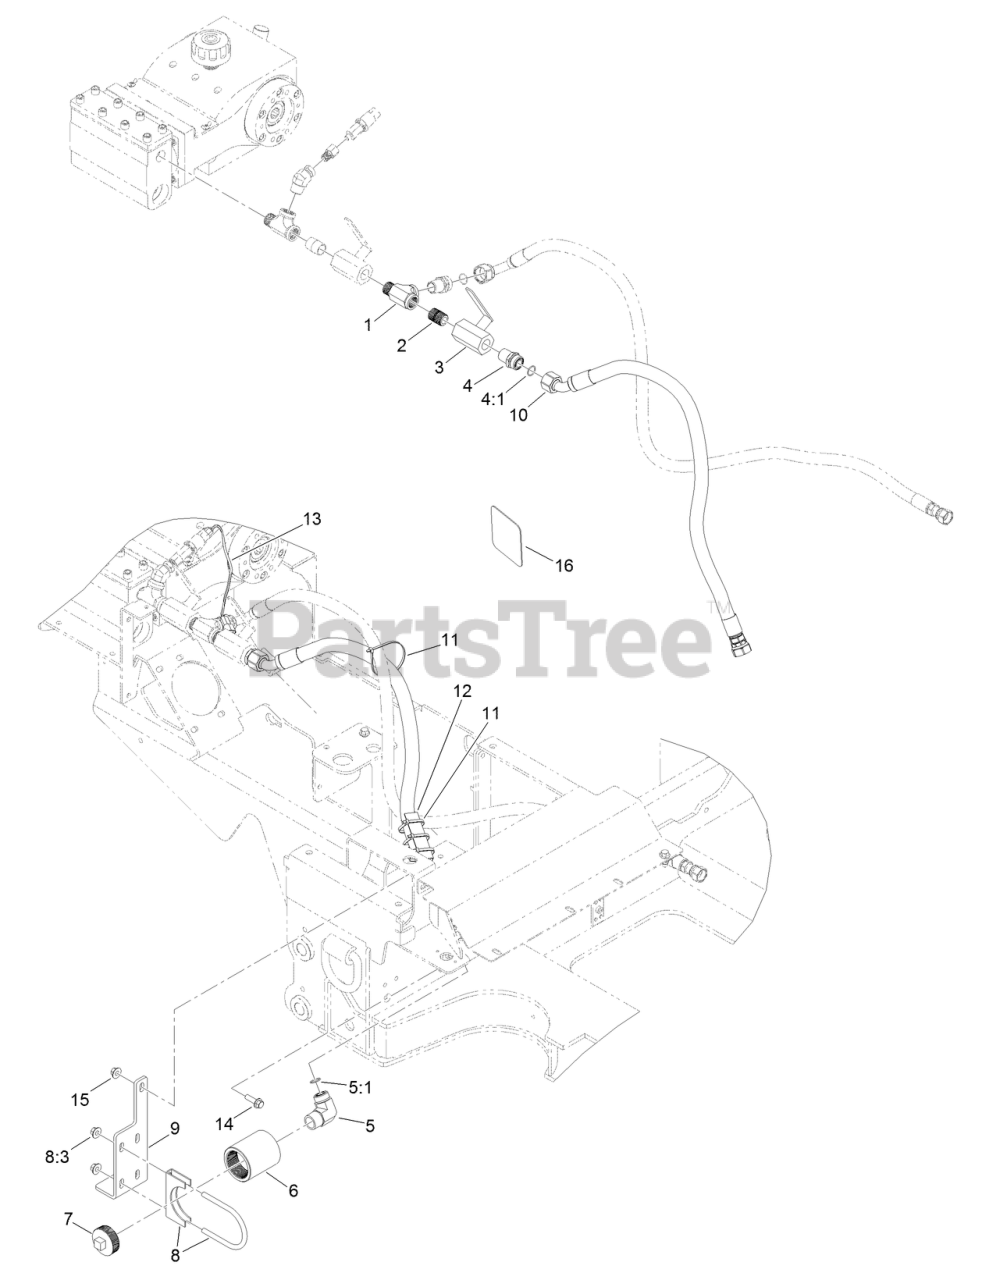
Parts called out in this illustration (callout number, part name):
1	FITTING-TEE
2	FITTING
3	VALVE-BALL
4	FITTING-STRAIGHT
4:1	O-RING
5	FITTING-ELBOW, 90
5:1	O-RING
6	FITTING-REDUCER
7	PLUG-PIPE, SQUARE HEAD
8	CLAMP-MUFFLER
8:3	NUT-FLANGE
9	BRACKET
10	HOSE ASM
11	TIE-CABLE
12	PROTECTOR-HOSE
13	HARNESS-WIRE
14	SCREW-HHF
15	NUT-HF, NI
